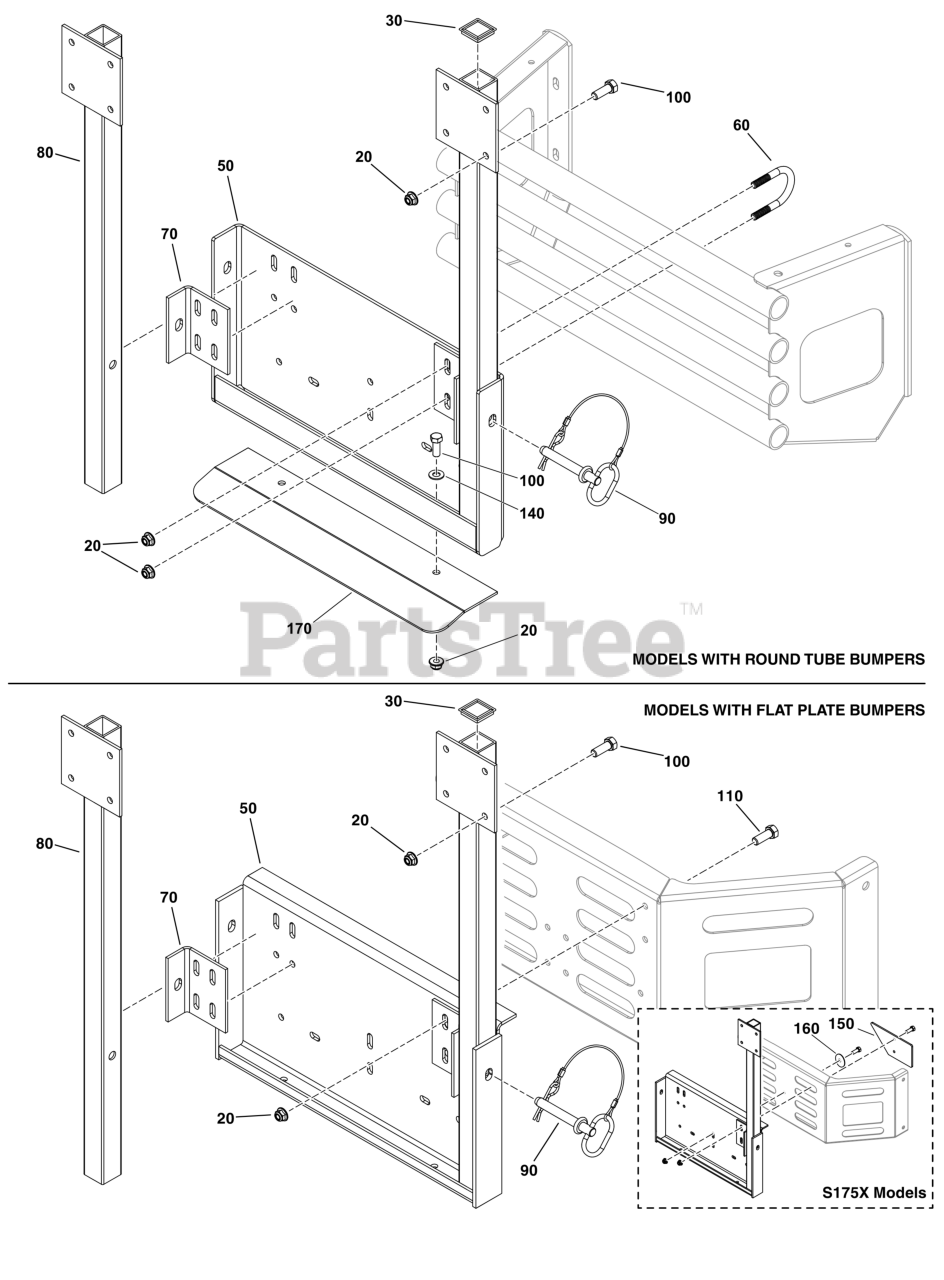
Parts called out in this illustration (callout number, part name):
20	NUT, 3/8-16 HEX NYLOCK
30	CAP, PLASTIC
50	MOUNT, BAGGER
60	U-BOLT, 3/8 X 1-1/4
70	BRACKET-MOUNTING
80	WELD, MOUNT, POST - B
90	PIN, HITCH, .50 X 3.2
100	BOLT, 3/8-16 X 1" GD5
110	BOLT, 3/8-16 X 1-1/4"
150	PLATE, SUPPORT
160	WASHER, .39 X 2.00 X
170	SHIELD, Heat
